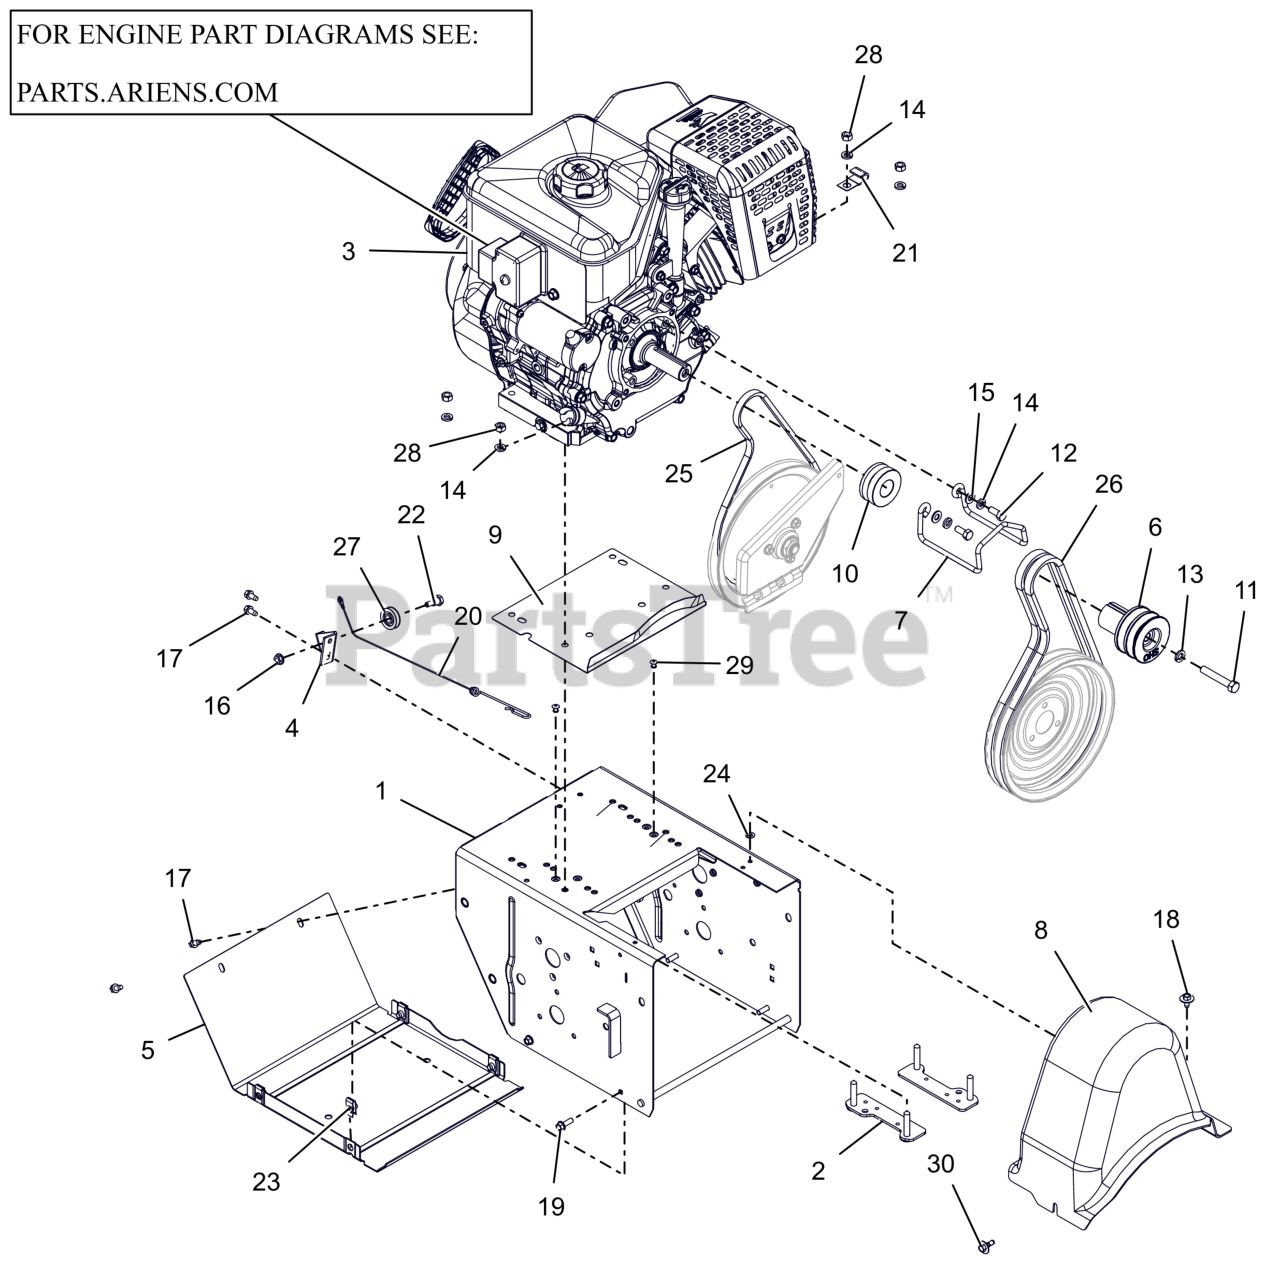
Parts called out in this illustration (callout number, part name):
1	FRAME, MAIN - 14GA DELUXE (ORANGE)
2	STRAP, BOLT-LARGE
3	ENGINE,EFI369 GEN3 120V/60W
4	BRACKET, CABLE PULLEY
5	COVER, BOTTOM
6	SHEAVE,ATTACHMENT-SHO 2 GRV
7	FINGER, BELT
8	COVER, BELT-LARGE
9	BAFFLE, WATER - LARGE BLOCK
10	SHEAVE, TRACTION (KEYLESS)
11	BLT, HEX .38-24X2.25 G5 ZCC
12	BLT, HEX .31-24X.750 G5 ZCC
13	WSHR,LK-REG .375X.094 ZCC
14	WSHR, LK-HVY .312X.097 ZCC
15	WSHR,FLT .344X.688X.065 ZCC
16	NUT-LK-TOP-FLG .250-20 GF ZCC
17	SCR-TAP .25-20X.50 HWH ZCC
18	SCR, TAP .25-20X.50 LG HWH ZCC
19	BLT, HWH .25-20X.75 G5 ZCC
20	CABLE, LOWER TRACTION,SS & PRO
21	J-CLAMP
22	BOLT, SHLDR -.375 X .375 X .25-20
23	NUT-RTNR .25-20X.56
24	NUT-PUSH .25X.50 O.D.
25	V-BELT, 3L-WRAPPED
26	V-BELT, HA-RAW EDGE (SET)
27	PULLEY, CABLE
28	NUT, HEX .312-18 ZCC
29	RVT, POP .1875 ZCC
30	SCR-TAP .25-20X.5 CAPTIVE
